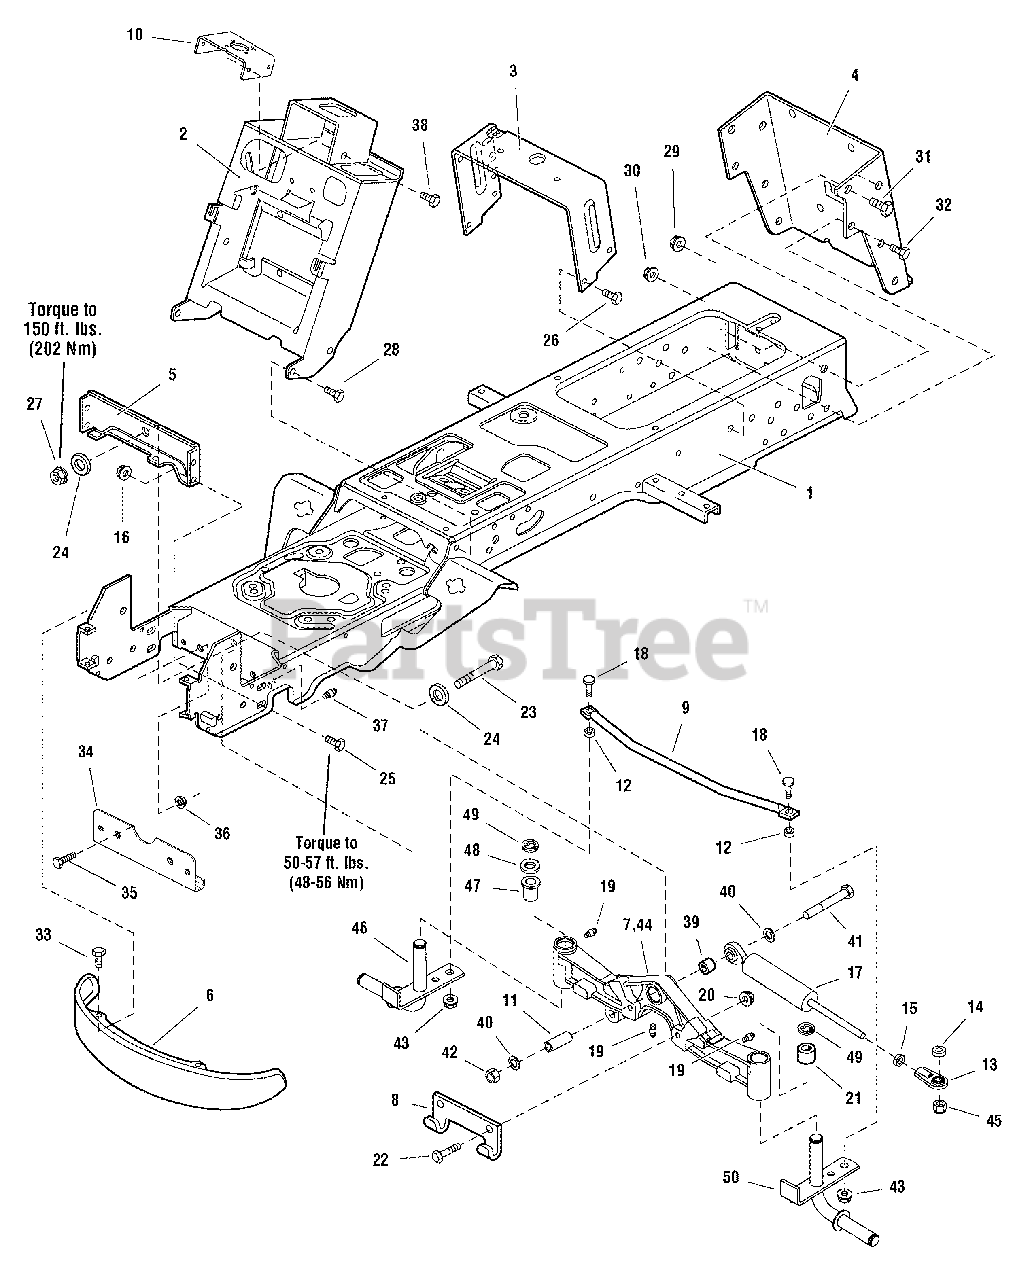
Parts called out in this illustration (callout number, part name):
1	FRAME ASSEMBLY, Front & Rear
2	TOWER & SUPPORT ASSEMBLY
3	SUPPORT, Seat Deck
4	BACKPLATE, Hitch
5	PLATE, Axle Support
6	BUMPER
7	AXLE, SPINDLES & BUSHINGS ASSEMBLY
8	HOOK, "J"
9	ROD, Tie, Flat Ends
10	SUPPORT, Steering Unit
11	SPACER, Powdered Metal
12	SPACER
13	JOINT, Ball, 1/2-20 Thread
14	SPACER
15	NUT, Hex Jam, 1/2-20
16	NUT, Hex Flange, 3/8-16 Two-Way Lock
17	CYLINDER, Hydraulic Steering
18	CARRIAGE BOLT, 3/8-16 x 1 G5
19	FITTING, Lube 1/4 Drive
20	NUT, Hex Flange 7/16-14 Two Way Lock
21	SPACER, Powdered Metal
22	CAPSCREW, Hex Head 7/16-14 x 2 G8
23	CAPSCREW, Hex Head 5/8-11 x 3-1/2 G5
24	WASHER, 5/8
25	SCREW, Hex Whiz Lock Flange 3/8-16 x 3/4
26	SCREW, Hex Washer Head Taptite 5/16-18 x 3/4
27	NUT, Hex Flange 5/8-11 Two Way Lock
28	SCREW, Hex Washer Head Taptite 3/8-16 x 3/4
29	NUT, Hex Flange 1/2-13 Whiz Lock
30	NUT, Hex Flange 3/8-16 Whiz Lock Large
31	CAPSCREW, Hex Head 1/2-13 x 1 G5
32	CAPSCREW, Hex Head 3/8-16 x 1 G5
33	SCREW, Truss Head Torx Drive 5/16-18 x 7/8
34	PLATE, Axle "U" Form
35	SCREW, Hex Whiz Lock Flange 5/16-18 x 3/4
36	NUT, Hex Flange 5/16-18 Whiz Lock
37	FITTING, Lube 1/4 Drive
38	SCREW, Hex Washer Head Taptite 5/16-18 x 1/2
39	SPACER
40	WASHER, 5/8
41	CAPSCREW, Hex Head
42	NUT, Hex Toplock
43	NUT, Hex Flange, Machine Lock 3/8-16
44	AXLE, Front Casting
45	NUT, Hex Lock ESNA Heavy 1/2-13
46	SPINDLE & ARM ASSEMBLY, R.H.
47	BUSHING, Axle
48	WASHER, 1
49	RING, Retaining, Extension
50	SPINDLE & ARM ASSEMBLY, L.H.
